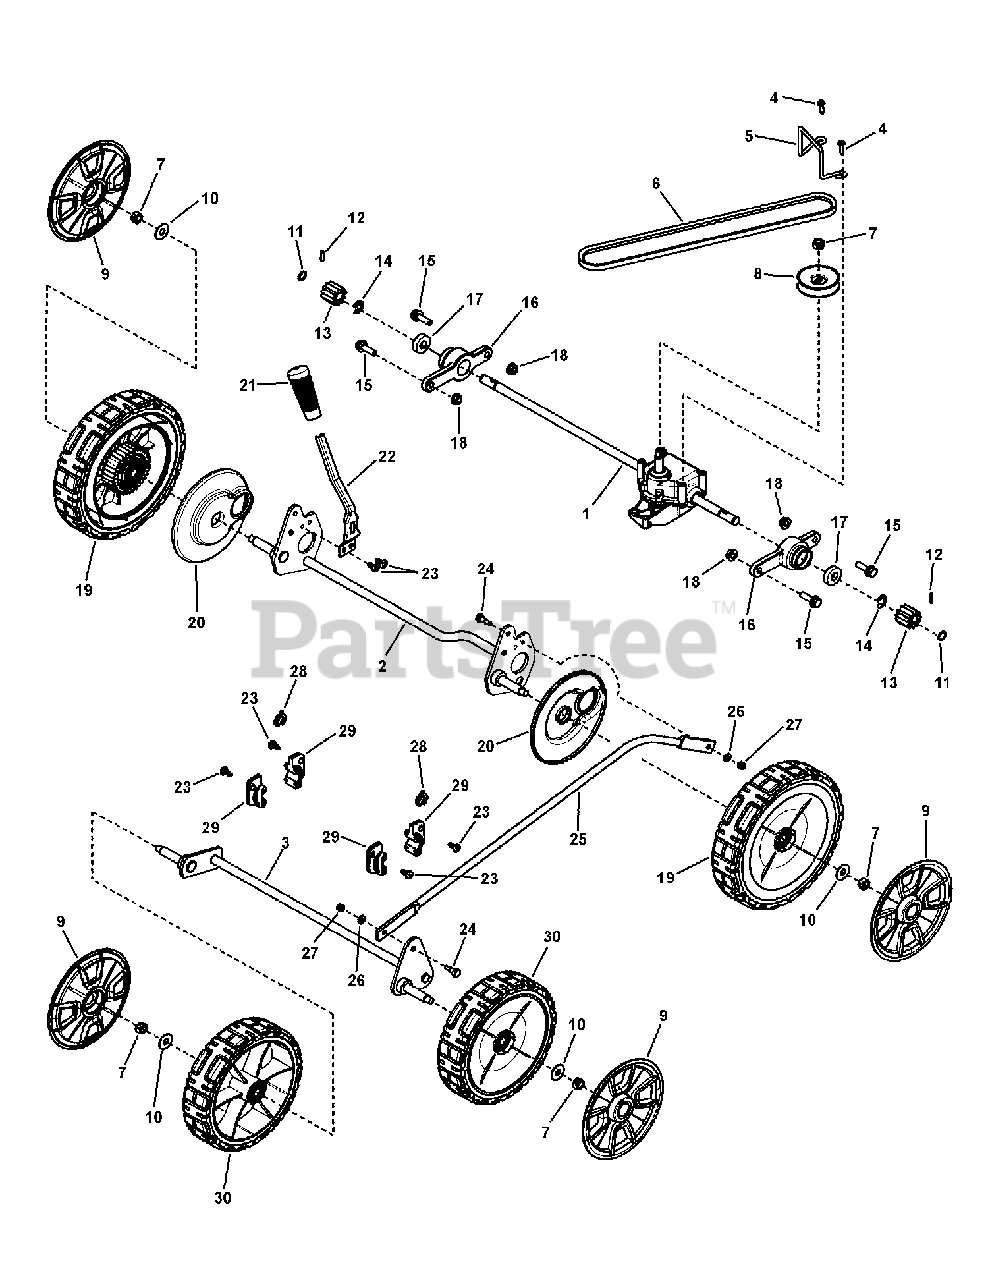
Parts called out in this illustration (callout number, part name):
1	TRANSMISSION, Variable Speed, Rear Wheel Drive
2	WELDMENT, Rear Crossbar, RWD
3	WELDMENT, Front Axle
4	SCREW, #10-16 x 3/4" Pan Head Self-Tap, Combo
5	BELT GUIDE, Transmission
6	BELT, 3L, Traction Drive, 22" WBM, RWD
7	NUT, 3/8-16 Hex Center Lock, YZ
8	PULLEY, Transmission Variable Speed, LC WBM
9	HUBCAP, 8" & 9" Spoked Wheel, Snapper Cool Gray
10	WASHER, 1" OD x .387 ID, Flat
11	RETAINING RING, .452 - .463 ID (Waldes Truarc 5100-50 or equivalent)
12	PIN, Axle
13	GEAR, Pinion
14	RETAINING RING (Waldes 5133-50 or equivalent)
15	BOLT, 5/16-18 x 1" Hex Flange Lock, GR 5
16	HOLDER, Bearing, Rear Wheel Drive
17	BALL BEARING, Axle
18	NUT, 5/16-18 Hex Flange Lock, GR 5
19	WHEEL ASSEMBLY, 9 x 2 Drive, Snapper Tread, w/Ext Gear
20	SHIELD, Dust, 21" WBM, RD
21	GRIP, Height-Of-Cut
22	LEVER, Spring, Height-Of-Cut
23	SCREW, 1/4-20 x .550 Pan Head Torx (T-30)
24	SHOULDER BOLT, #10-24
25	ROD, Lifter Link, WBM
26	WASHER, .219 x .500 x .049 Flat
27	NUT, #10-24 UNC-2B Nyloc
28	SPACER, Shaft, 1/2"
29	BUSHING, Bearing, Rear Wheel Drive
30	WHEEL ASSEMBLY, 8 x 2 Idle, Snapper Tread, BB, Charcoal Gray
